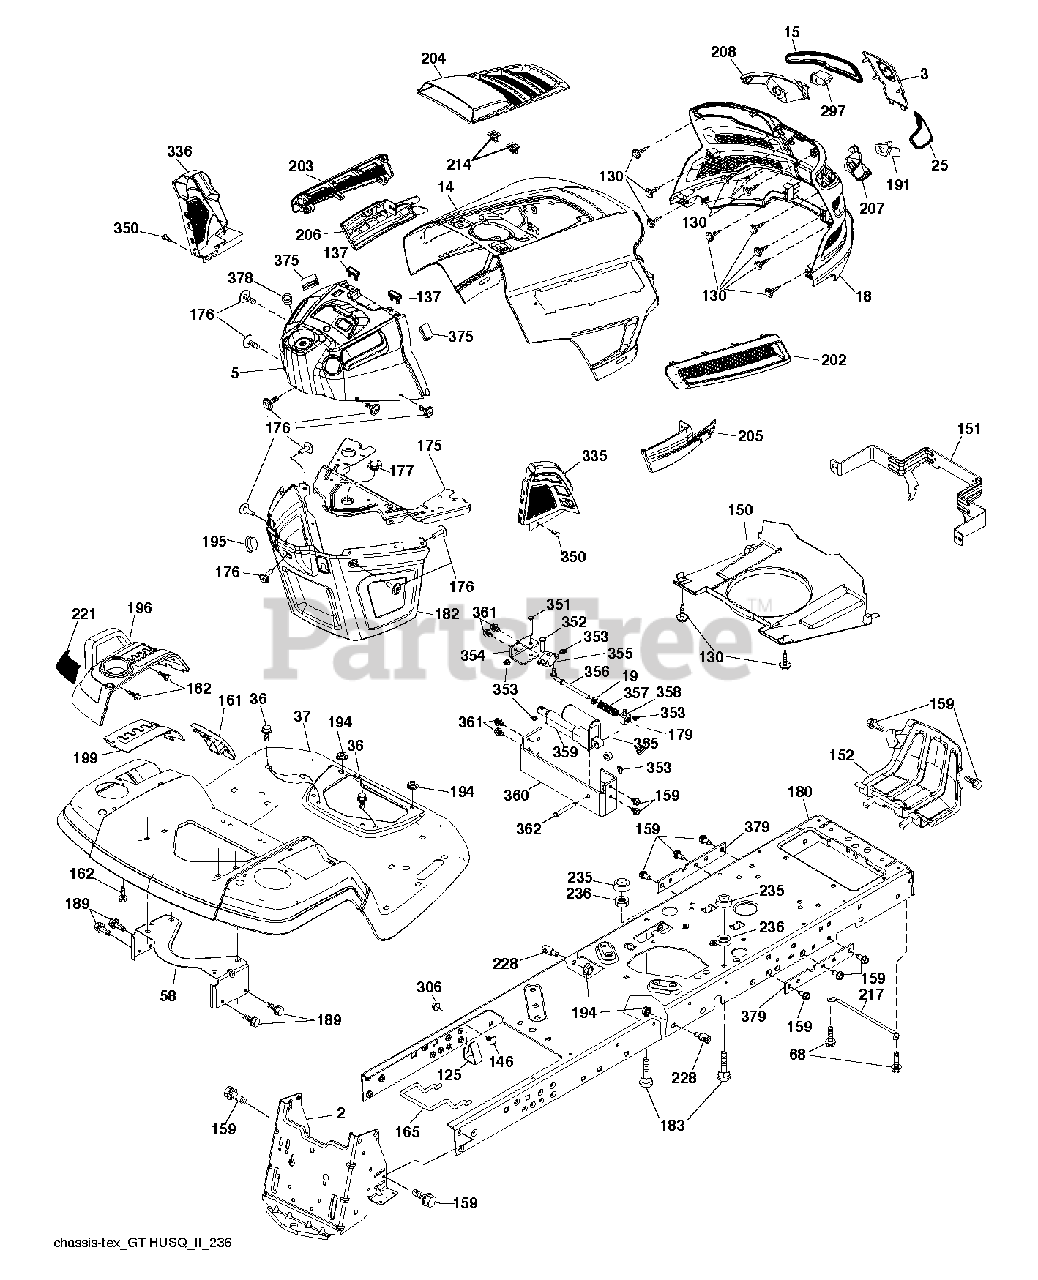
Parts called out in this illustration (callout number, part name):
2	DRAWBAR.STGT
3	APPLIQUE.SUBASM.GT.HUSQ.II
5	DASHBOARD.TEX.GT2.UPPER.S.PTO
14	HOOD.ASM.HUSQVARNA.GT.TEX.ORAN
15	LENS.HEADLIGHT.LH.GTII.2011
18	GRILLE.SUBSTRATE.2011.
19	WASHER
25	LENS.HEADLIGHT.RH.GTII.2011
36	SCREW 5/16"
37	FENDER.PNT.TX.GT.CH/FW/DL.HUSQ
58	BRKT.SUPPORT.FNDR/TANK
68	SCR 5/16-18 X 1/2 SELFTAP ZN
125	CLIP.FUEL.LINE
130	SCREW.#10 X 0.750.BOS
137	BUMPER DASH
146	BOLT.RDHD.SHT.SQNK.3/8-16X5/8
150	AIR.DUCT.GTV.BLACK
151	BRACKET.PIVOT.HOOD.GT.HUSQ.II
152	SHIELD.BROWNING.PNT.GT.V2
159	SCREW, 3/8-16X3/4
161	CONSOLE.WINDOW.FUEL.HUSQ.GT
162	SCREW.HI-LO.CONSOLE
165	SUPPORT.TANK.REAR.B/TE
175	Crossmember Plate
176	SCREW.#10-24X5/8.RN.QU
177	BUSHING STEERING
180	CHASSIS.LT/GT.BOLTED
182	DASH.LOWER.COMMON.12V.ADAPTOR
183	BOLT.5/16-18X1-1/4 FULL THD
189	SCREW
191	INSERT.REFLECTIVE.RH.HUSQ.GTII
194	NUT LOCK HEX FLANGE 5/16-18
195	PLUG.HOLE.DASH.LOWER.12V.BLK
196	CONSOLE.ASM.DECKLIFT.HUSQGT.DL
199	PLATE.DECK.LIFT.HUSQVARNA.GT
202	VENT.SIDE.RH.GT.HUSQ.II.
203	VENT.SIDE.LH.GT.HUSQ.II.498
204	VENT.TOP.HUSQ.GT2
205	SIDE.TRIM.RH.GT.HUSQ.II
206	SIDE.TRIM.LH.GT.HUSQ.II.GRAY
207	BEZEL LIGHT.RH.GT.II.MYLAR
208	BEZEL LIGHT.LH.GT.II.MYLAR
214	CLIP.RETAINER.TINNER.
217	ROD.PIVOT.HOOD
221	REFLECTOR.LH.TEX GT HU
228	STUD.FASTNER.W/ANTI-ROTATE
235	SPACER FENDER
236	NUT.CENTERLOCK.5/16-
297	INSERT.REFLECTIVE.LH.HUSQ.GTII
306	NUT LOCK FLG 3/8-16 UNC
335	COVER.LOWER.DASH.RH.BLACK
336	COVER-LH.LOWER.DASH.GT2.BLACK
350	CLIP.X-MAS.TREE
351	PIN.CLEVIS.375X2.125
352	PIN.CLEVIS.(.375 X 1.25)
353	CLIP RETAINER
354	SUPPORT.BELLCRANK
355	BELLCRANK.PIVOT.LOCK.DIFF
356	LINK.LOCK.DIFF
357	SPRING.COMPRESSION
358	GUIDE.SWIVEL
359	ACTUATOR.ELECTRIC
360	BRACKET.ACUATOR
361	SCREW LT.3/8-46X5/8
362	PIN.CLEVIS.(.375 X 2.42)
365	SPACER.NYLON.75" X .4375
375	BUMPER CLIP-ON. DASH 1"
378	BUSHING FLANGE; PLASTIC
379	CHASSIS.PLATE.REINFORCEMNT.431
